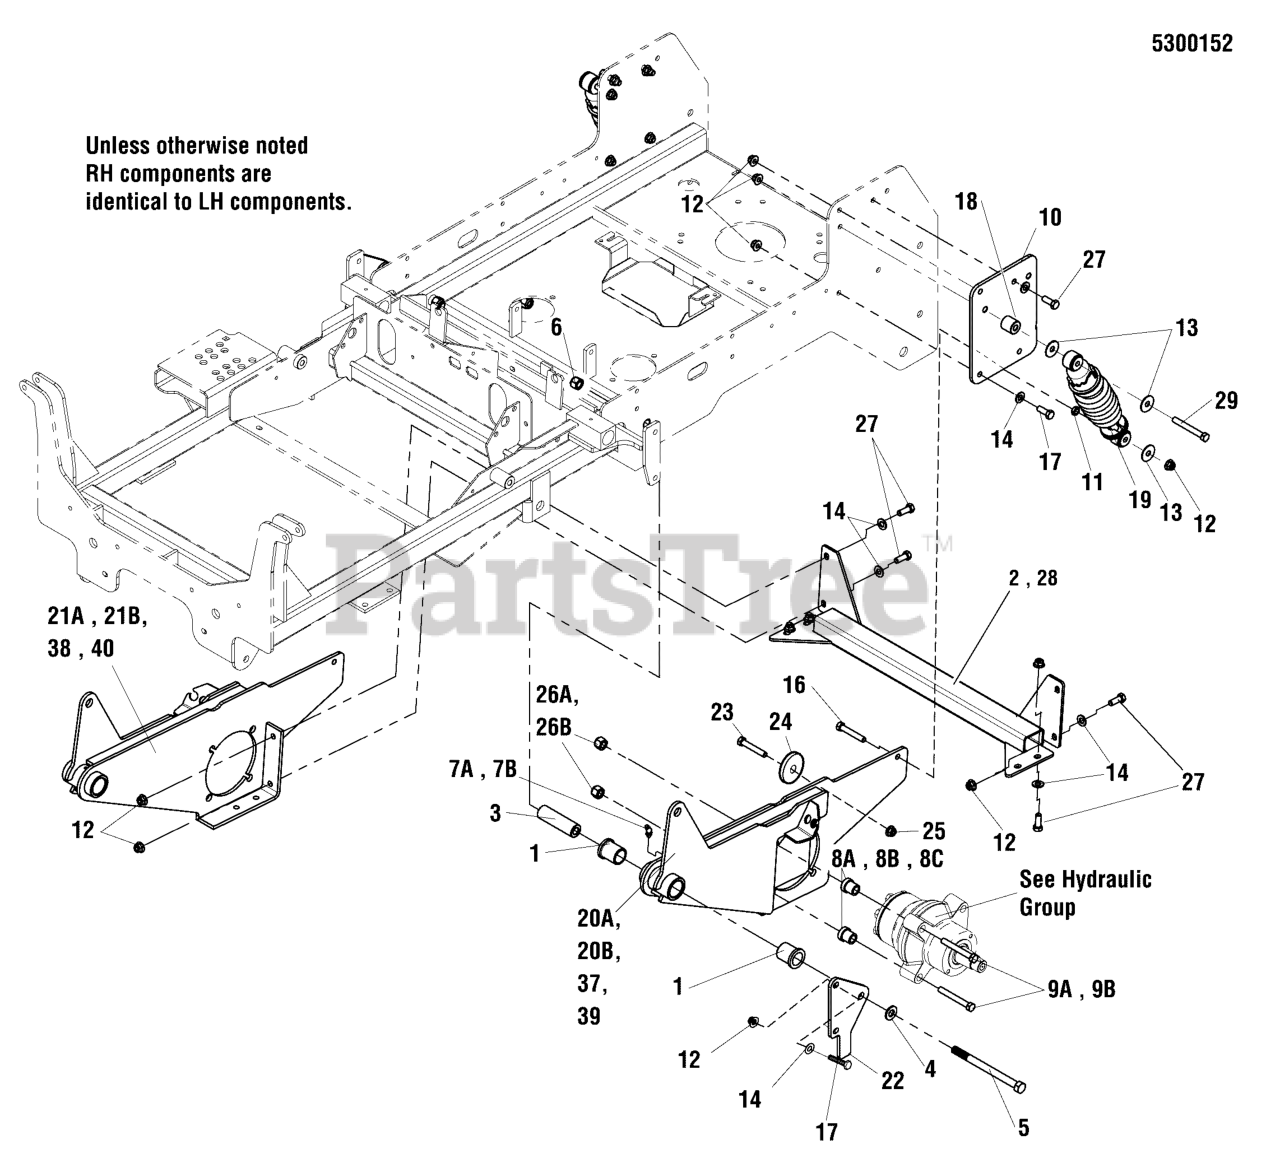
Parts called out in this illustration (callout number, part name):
1	BUSHING, FLANGE
2	KIT, TIE BAR, 52
3	SPACER, .52 X 1.00 X 3.42
4	WASHER, 1/2 GD9 YZ
5	BOLT, 1/2-13 X 6-1/2 GD8, YZ
6	NUT, 1/2-13 HEX NYLON LOCK
10	PLATE, FRAME SUPPORT, LH - RED
11	SPACER, .39 X 1.00 X .50
12	NUT, 3/8-16 HEX NYLOCK FLANGE
13	WASHER, 3/8" FENDER
14	WASHER, 3/8 GD.9 FLAT
15	BOLT, 3/8-16 X 3" GD5 CZ
16	BOLT, 3/8-16 X 2-1/4" GD5 CZ
17	BOLT, 3/8-16 X 1" GD5 CZ
18	SPACER, .39 X 1.00 X 1.25, CZ
19	COIL - OVER SHOCK ASSEMBLY
22	SUPPORT, SWING ARM - BLK
23	SCREW, 5/16-18 X 1, PHILLIPS HD, BZ
24	SPACER, .34 X 1.54 X .25 UHMW
25	NUT, 5/16-18 HEX NYLOCK FLANGE
27	BOLT, 3/8-16 X 1-1/4" GD5 CZ
28	KIT, TIE BAR, 61
29	BOLT, 3/8-16 X 3-1/2" GD5 CZ
37	WELD, MOTOR MOUNT, LH - RED
38	WELD, MOTOR MOUNT, LH - RED
39	WELD, MOTOR MOUNT, RH - RED
40	WELD, MOTOR MOUNT, RH - RED
